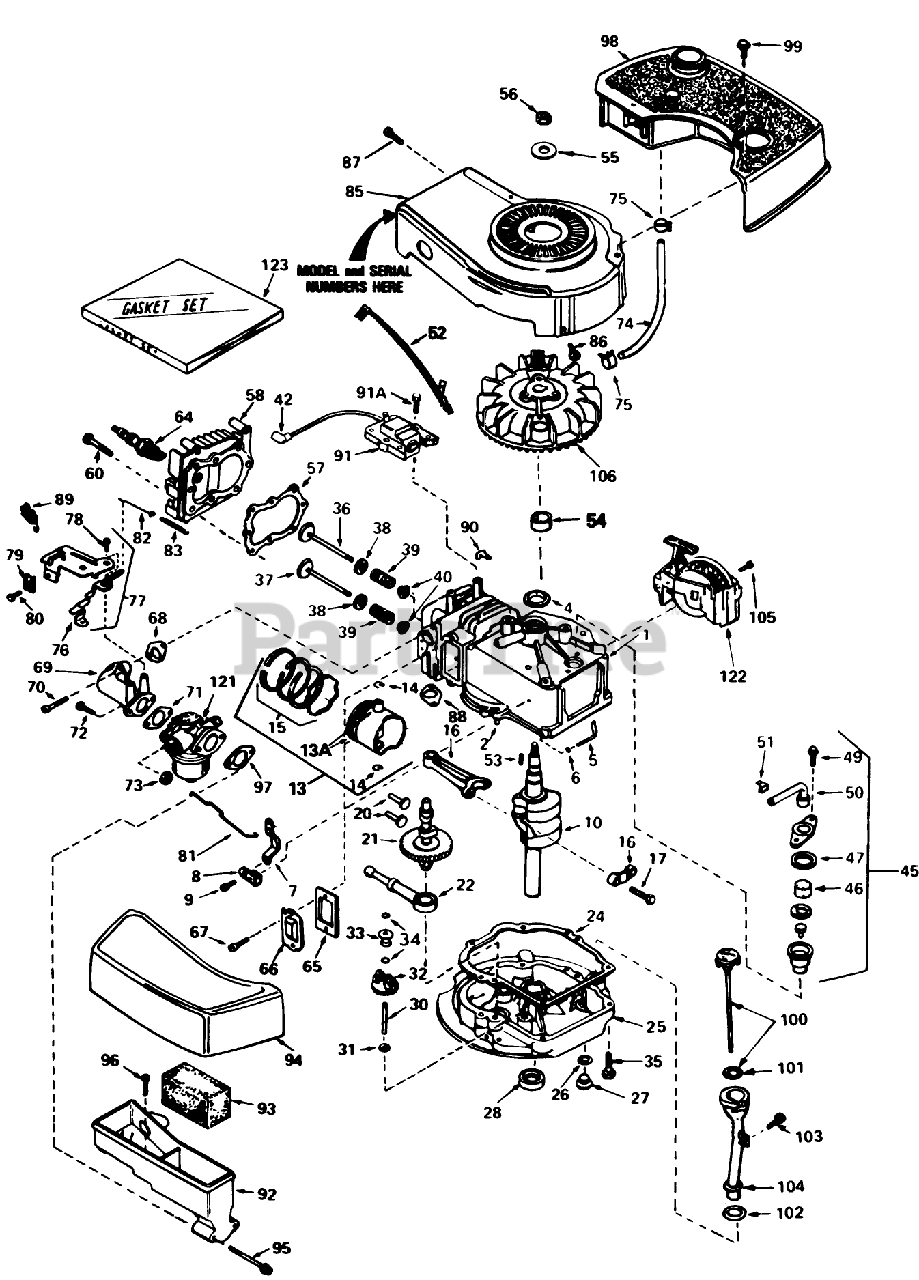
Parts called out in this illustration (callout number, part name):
1	Cyiinder Assy. (Incl. Ref. #2, 4 105)
2	Pin-Dowel
4	Seal-Oil
5	Rod, Governor (Incl. No. 36)
6	Washer-Flat
7	Governor Lever
8	Clamp-Lever, Governor
9	Screw
10	Crankshaft
13	Piston, Pin Ring Assy. (Std.) (Incl. Ref. #13A, 14 15)
13	Piston, Pin Ring Assy. (.010 oversize) (Incl. Ref. #13A, 14 15)
13	Piston, Pin Ring Assy. (.020 oversize) (Incl. Ref. #13A, 14 15)
13A	Piston Pin Assy. (Incl . Ref. . #14) (Std.)
13A	Piston Pin Assy. (Incl. Ref. #14) (.010 Oversize)
13A	Piston Pin Assy. (.020 oversize) (Incl. Ref. #14)
14	Ring-Retaining, Piston Pin
15	Ring Set (Std.)
15	Ring Set (.020" OS)
15	Ring Set (.010" OS)
16	Rod Assy., Connecting (Incl. Ref. #17)
17	Bolt-Rod, Connecting
20	Lifter-Valve
21	Camshaft(Mech.Comp. Release)
22	Oil Pump ASM
24	Gasket, Mounting
25	Flange Assy., Mounting (Incl. Ref. #26thru 30)
26	Gasket-Oil Drain
27	Plug Oil Drain
28	Seal Oil
30	Shaft-Governor
31	Washer-Flat
32	Governor Gear ASM
33	Spool-Governor
34	Ring-Retaining
35	Screw (1/4-20 x 1-1/4)
36	Valve, Intake (Std.) (Incl. Ref. #40)
36	Valve, Intake (1/32" oversize)(Incl. No. 40)
37	Valve, Exhaust (Std.)(Incl. No. 40)
37	Valve, Intake (1/32" oversize)(Incl. No. 40)
38	Cap-Upper Valve Spring
39	Spring-Valve
40	Cap-Valve, Spring
42	Cover-Spark Plug
45	Breather Assy. (Incl. Ref. #46 thru 51)
46	Element-Breather
47	Gasket-Breather
49	Screw (10-24 x 9/16)
50	Tube, Breaker
51	Clip, Breather
52	Wire-Ground
53	Key-Flywheel
54	Spacer
55	Washer-Belleville
56	Nut-Flywheel
57	63573 GIL 42 SNWTHW
58	Head-Cylinder
60	Screw (5/16-18x1-1/2)
64	Plug, Spark (J17LM or equiv.)
64	Plug, Spark (Champion RCJ-8)
65	Gasket-Breather
66	Cover-Valve
67	Screw
68	Gasket-Intake
69	Pipe, Intake (Incl. No. 68)
70	Screw (1/4-20 x 1)
71	Gasket-Carburetor
73	Nut and Lock Washer (1/4-28)
74	Line-Fuel
75	Clamp-Line, Fuel
76	Lever Control
77	Control Assy., Speed (Incl. Nos, 76, 78 89)
78	Screw, Hex Washer Hd Shoulder Self-Tap
79	Conduit
80	Screw (10-32 x 3/8)
81	Link-Throttle
82	Link Governor Spring
83	Spring Governor
85	Housing-Blower
86	Screw (1/4-20x19/32)
87	Screw (10-24 x 9/16)
88	Gasket Exhaust
89	Terminal
90	Clip-Wire
91	Solid State
91A	Screw
92	Body Air Cleaner
93	Filer, Air
94	Cove, Air Cleaner
95	Screw Fil Hd.
96	Screw, Hex Hd.
97	Gasket-Air Cleaner
98	Tank-Fuel
99	Screw (10-32 x 35/64)
100	Dipstick, Oil (Incl. Ref. #101)(Twist Lock)
101	O-Ring
102	Gasket
103	Screw (10-32 x 1/2)
104	Tube-Oil Fill
105	Screw (1/2-20x5/8)
106	Flywheel
121	Carburetor (Incl. Ref. #71)
122	Starter-Sidemount
123	Gasket Set
